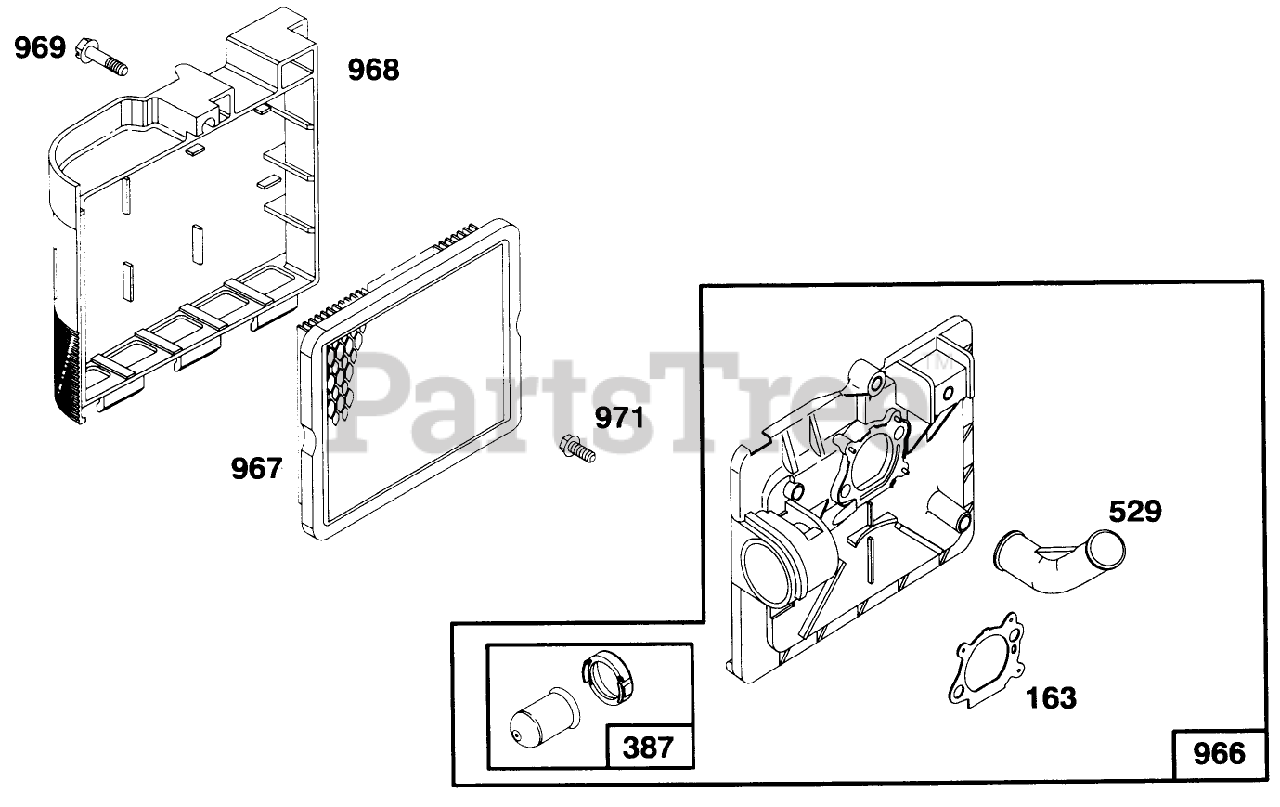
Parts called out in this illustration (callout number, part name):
163	Gasket-Cleaner, Air
387	CarburetorPrimer
529	Grommet
966	Base-Primer, Air Cleaner
967	Filter-Air Cleaner, Cartridge
968	Air Cleaner Cover
969	Screw-Cover Mt.
971	Screw-Air Cleaner
